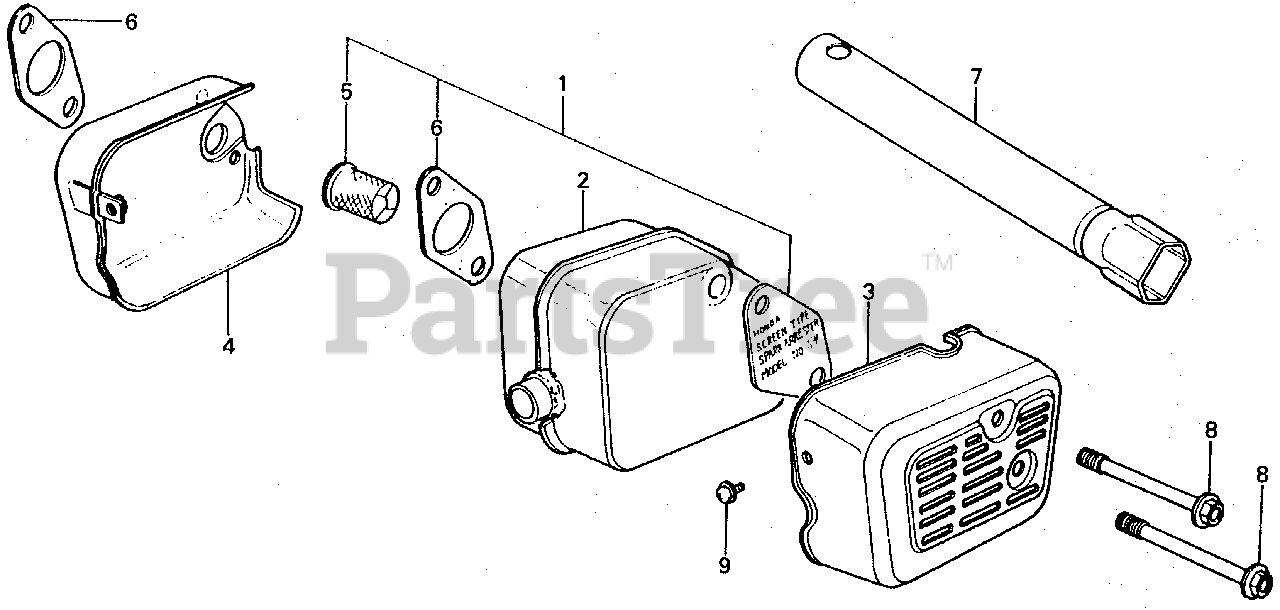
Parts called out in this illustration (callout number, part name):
1	ARRESTER KIT, SPARK
3	PROTECTOR, MUFFLER
4	SEPARATOR, MUFFLER
5	ARRESTER KIT, SPARK
6	GASKET, MUFFLER
7	WRENCH, SPARK PLUG (NOT AVAILABLE)
8	BOLT, FLANGE (8X100)
9	SCREW-WASHER (5X10)
